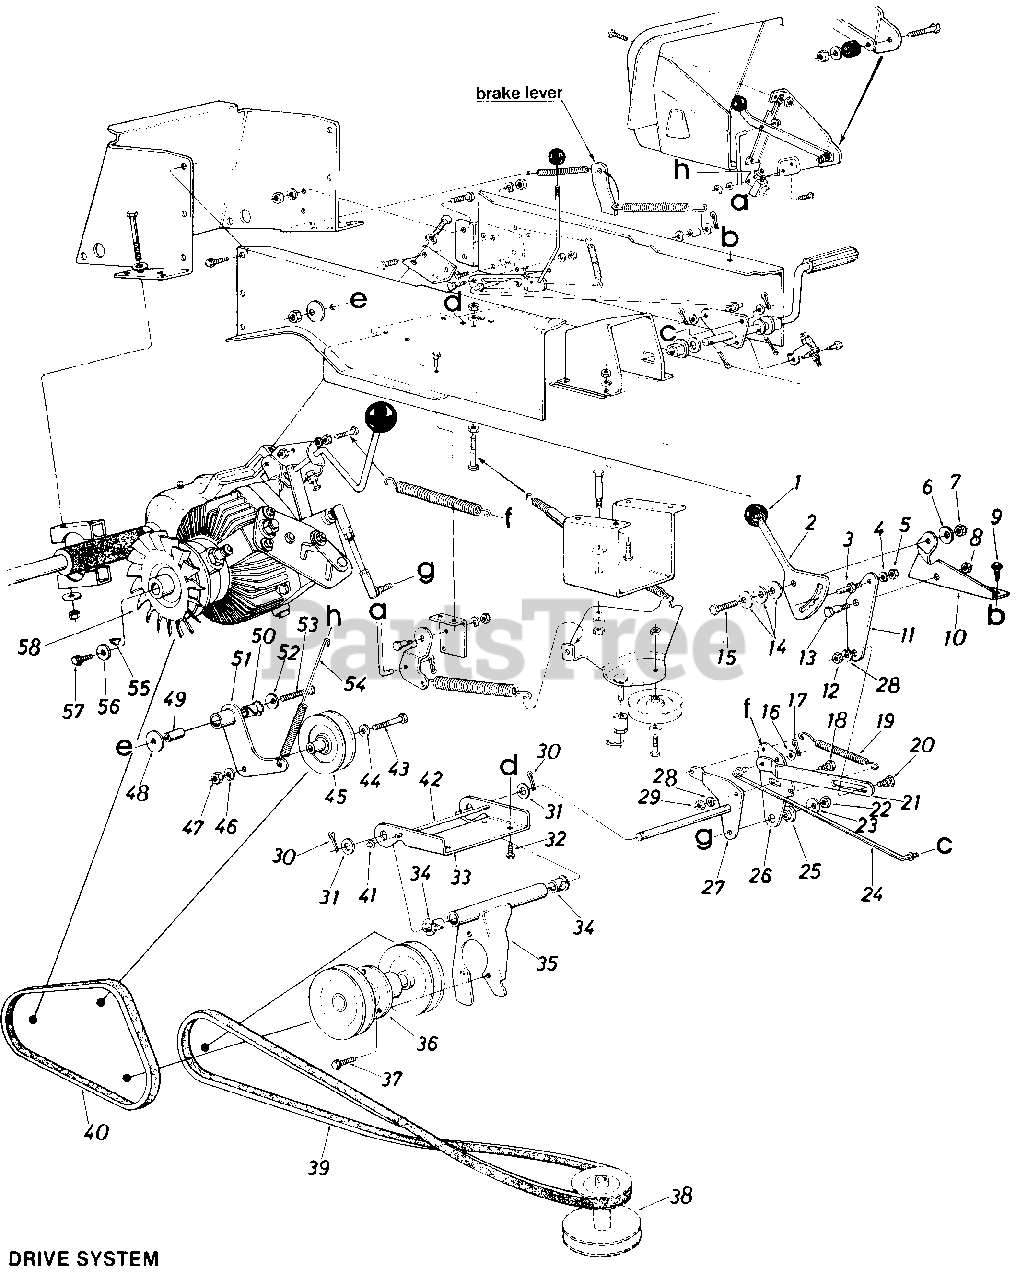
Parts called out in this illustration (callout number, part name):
1	Gear Shift Knob
2	Speed Selector Cam
3	Hex Stud .250" Dia. x .62"
4	L-Wash. 1/4" I.D.
5	Hex Nut 1/4-20 Thd.*
6	Bell-Wash. .400" I.D. x 1.13" O.D.
7	Hex Ins. L-Nut 3/8-24 Thd.
8	Hex Top L-Nut 3/8-16 Thd.
9	Hex Wash. Hd. S-Tap Scr. 1/4-20 x .75" Lg.
10	Speed Selector Mtg. Brkt.
11	Speed Selector Transfer Brkt.
12	Hex Nut 5/16-18 Thd.
13	Shld. Bolt .500" Dia. x .170
14	Bell-Wash. .39" I.D. x 1.13"O.D.
15	Hex Bolt 3/8-24 x 1.00" Lg.
16	Fl-Wash. .385" I.D. x .87" O.D.
17	Cotter Pin 3/32" Dia. x .75" Lg. *
18	Shld. Bolt .437" Dia. x .180
19	Extension Spring .50" Dia. x 2.75" Lg.
20	Shld. Bolt .437" Dia. x .180
21	Speed Selector Link
22	Hex Top L-Nut 3/8-24 Thd.
23	Bell-Wash. .39" I.D. x 1.13" O.D.
24	Rod-Speed Control .312" Dia.
25	Shld. Spacer.625" I.D.
26	Speed Cont. Transfer Swivel Brkt.
27	Speed Control Transfer Ass'y.
28	L-Wash. 5/16" I.D.
29	Hex Nut 5/16-18 Thd.
30	Cotter Pin 1/8" Dia. x 1.00" Lg. *
31	Fl-Wash. .69" I.D. x 1.24" O.D.
32	Hex Wash S-Tap Scr. 1/4-20 x .50" Lg.
33	Idler Mtg. Brkt.
34	Flanged Nyliner Brg. .376 I.D. x .437
35	Mounting Brkt. Ass'y.
36	Jack Shaft Ass'y.
37	Hex Sems Bolt 5/16-18 x .75" Lg.*
38	Engine Pulley 47.5" I.D. x 5.56" O.D.
39	"V"-Belt 1/2" x 59.0" Lg.
40	'V"-Belt 1/2" x 32.0" Lg.
41	Push Cap
42	Rod-3/16" Dia. x 7.12" Lg.
43	Hex Bolt 3/8-24 x 1.50" Lg.
44	Fl-Wash. .385" I.D. x .87"O.D.
45	Idler Pulley 4.0" O.D. x 5/8"-"V"
46	L-Wash. 3/8" I.D.
47	Hex Nut 3/8-24 Thd.*
48	Bell-Wash. .40" I.D. x .87" O.D.
49	Spacer.38" I.D. x .62" O.D. x 1.87" Lg.
50	Flanged Nyliner Brg.
51	Idler Pivot Brkt. Ass'y.
52	Fl-Wash. .385" I.D. x .87" O.D.
53	Hex Bolt 3/8-24 x 2.00" Lg.
54	Extension Spring .56" O.D. x 7.75" Lg.
55	#9 Hi-Pro Key .316" x .75"
56	Fl-Wash. .25" I.D. x .983" O.D.
57	Hex Wash. Hd. TT-Tap Scr. 1/4 x .75" Lg.
58	Trans. Pulley and Fan Ass'y .
